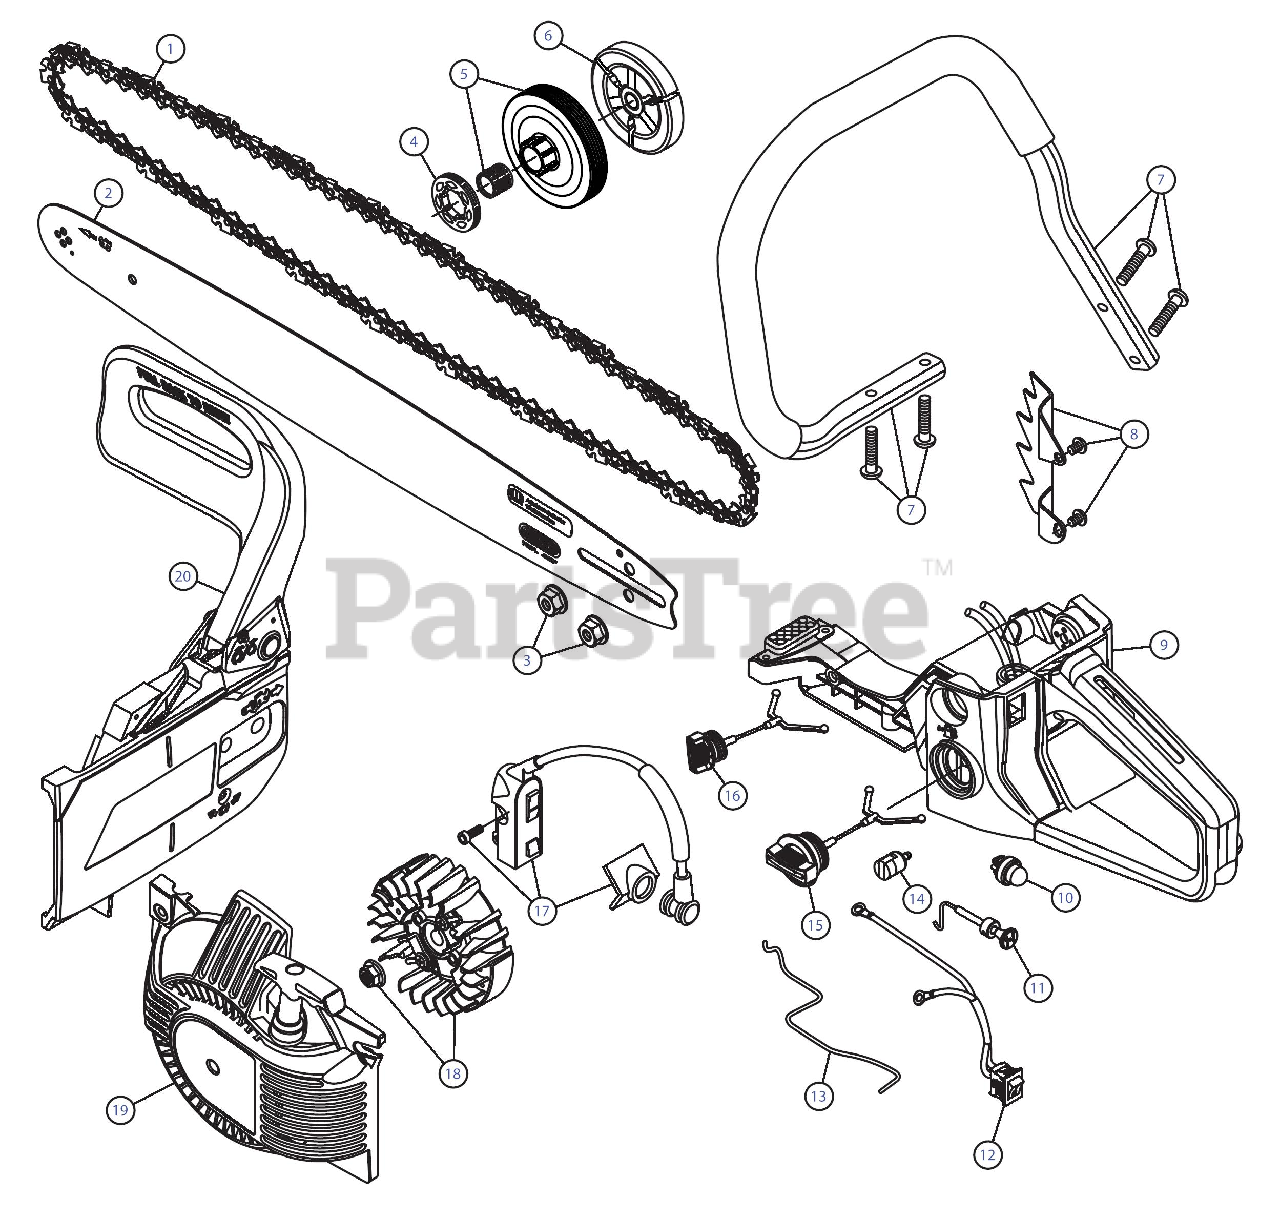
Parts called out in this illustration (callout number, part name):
1	Chain 18"
2	Chain Guide Bar
3	Guide Bar Nuts (2)
4	Sprocket
5	Clutch Drum Assembly
6	Clutch Assembly
7	Chainsaw Handle Assembly (with Screws (4))
8	Spike Plate (with Screws (2))
9	Fuel Tank Assembly
10	Primer Bulb
11	Choke Lever Assembly
12	Stop Switch Assembly
13	Throttle Rod
14	Fuel Filter
15	Fuel Cap Assembly
16	Oil Cap Assembly
17	Ignition Module Assembly (with Screws (2))
18	Flywheel Assembly
19	Starter Housing Assembly
20	Chainsaw Brake Assembly
